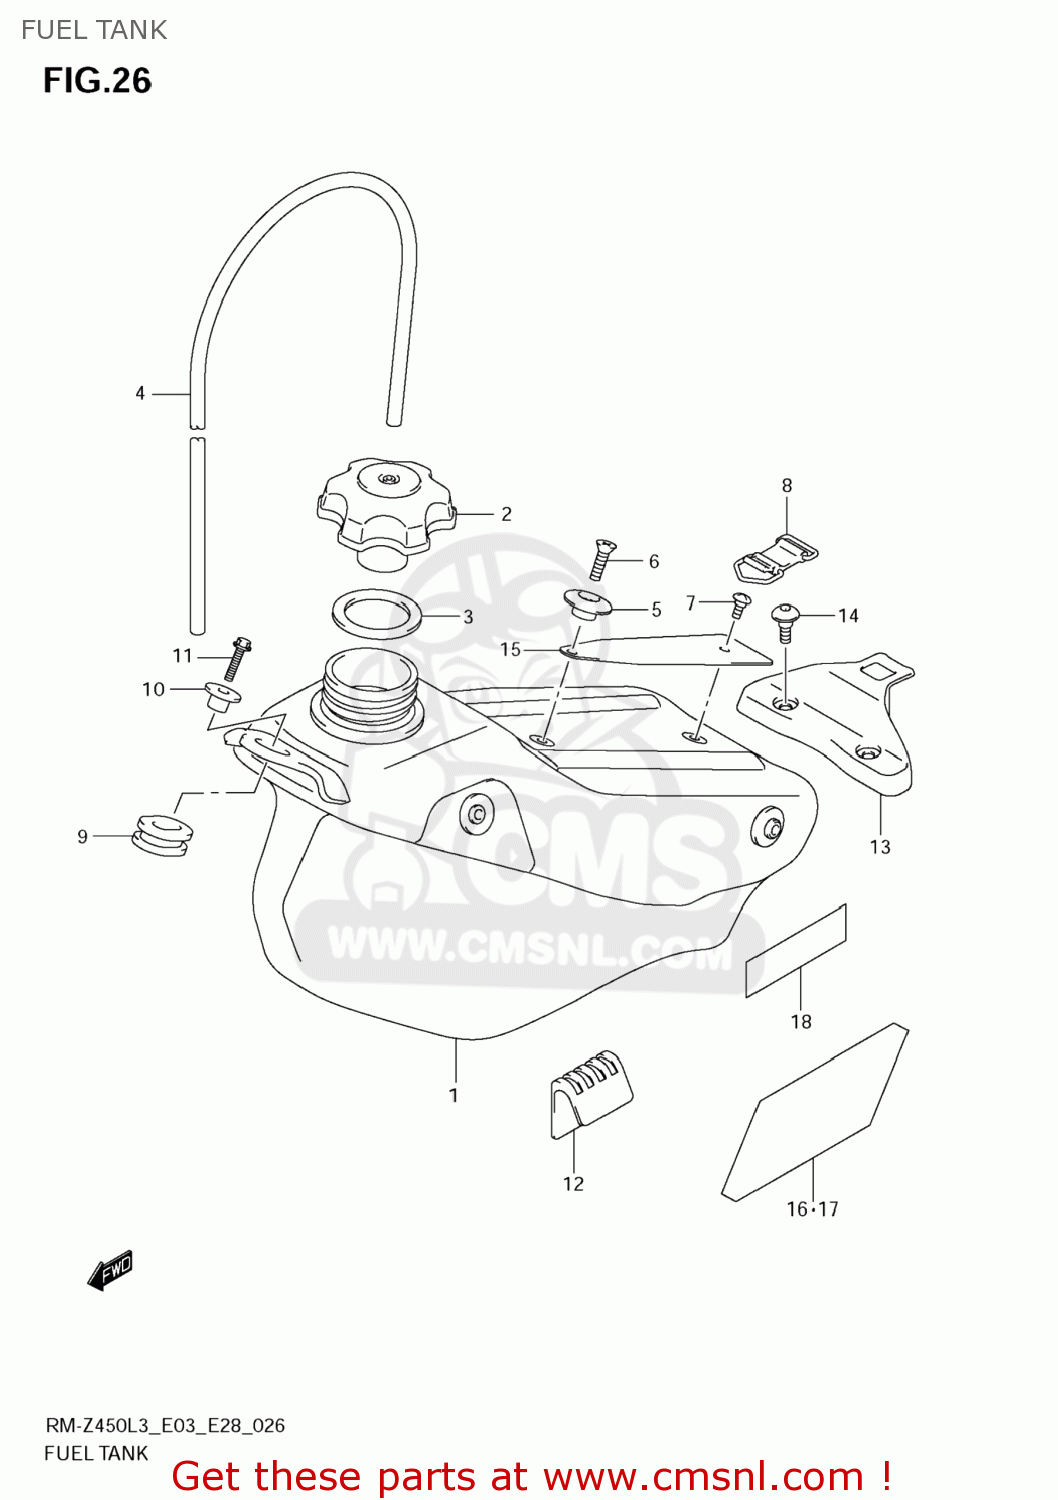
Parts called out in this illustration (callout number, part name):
1	TANK,FUEL
2	CAP,FUEL TANK FILLER
3	GASKET,CAP (NAS)
4	HOSE(5X8.2X600)
5	HOOK,SEAT FR
6	SCREW
7	SCREW(6X13.5)
8	BAND,FUEL TANK RR
9	CUSHION,FUEL TANK FR
10	SPACER
11	BOLT(6X30)
12	CUSHION,FUEL TANK SIDE
13	CUSHION,FUEL TANK RR
14	BOLT(5X13)
15	PROTECTOR,FUEL TANK
16	PROTECTOR,RADIATOR,R
17	PROTECTOR,RADIATOR,L
18	PROTECTOR,RADIATOR
